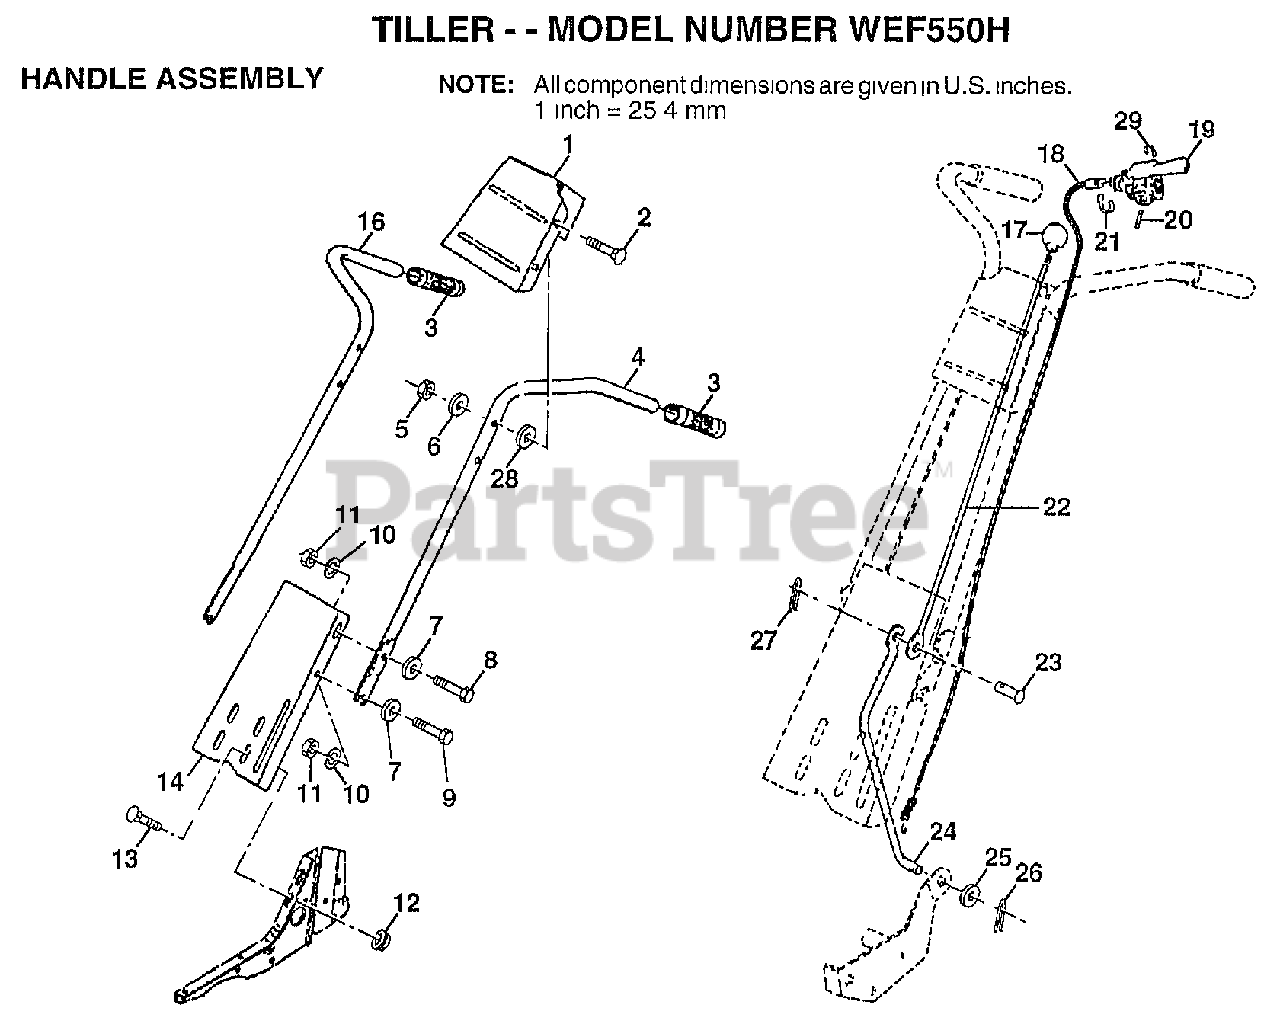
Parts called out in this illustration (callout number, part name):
1	BRACKET.HDLE.TILL
2	BOLT
4	HANDLE.LH TILLER
6	WASHER
7	WASHER
9	BOLT
10	LOCKWASHER
11	NUT.HEX.5/16-18
12	NUT
13	BOLT
14	PANEL.HANDLE.PNT.
16	"HANDLE-RH,TILLER"
17	KNOB T(3/8 HOLE)
18	CABLE CLUTCH T
19	LEVER CONTRL TINE
20	"PIN PIVOT,GROOVED"
21	E-RING
22	ROD REVERSE TI
23	RIVET.RD.HD.DRILL
24	REVERSE ROD TI
25	WASHER
26	COTTER PIN
28	WASHER
29	RETAINER RING
